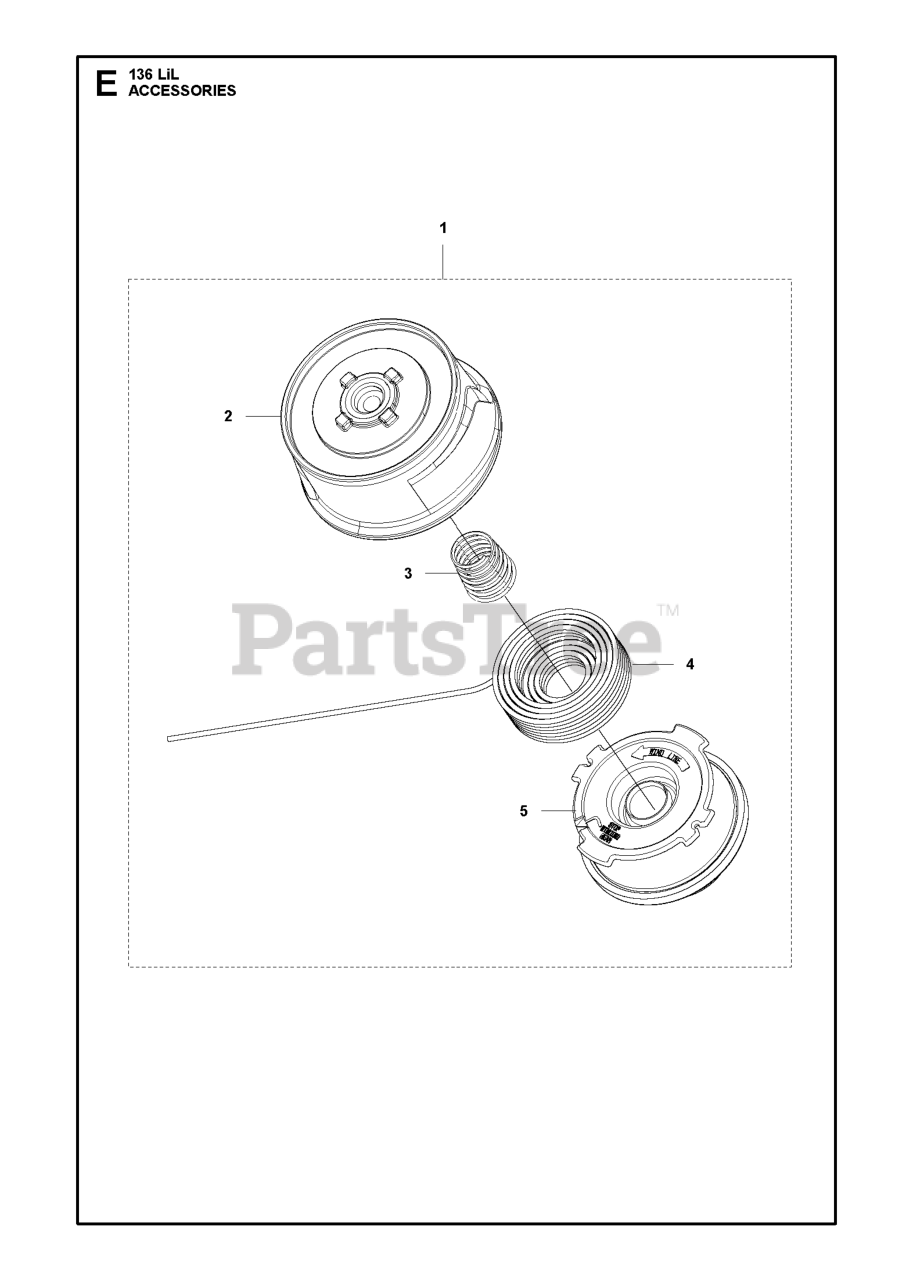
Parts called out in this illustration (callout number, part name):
1	HEAD CUTTING ASSEMBLY
2	HUB HUB ASSEMBLY
4	TRIMMER LINE TYST 2.0
5	SPOOL SPOOL ASSEMBLY
